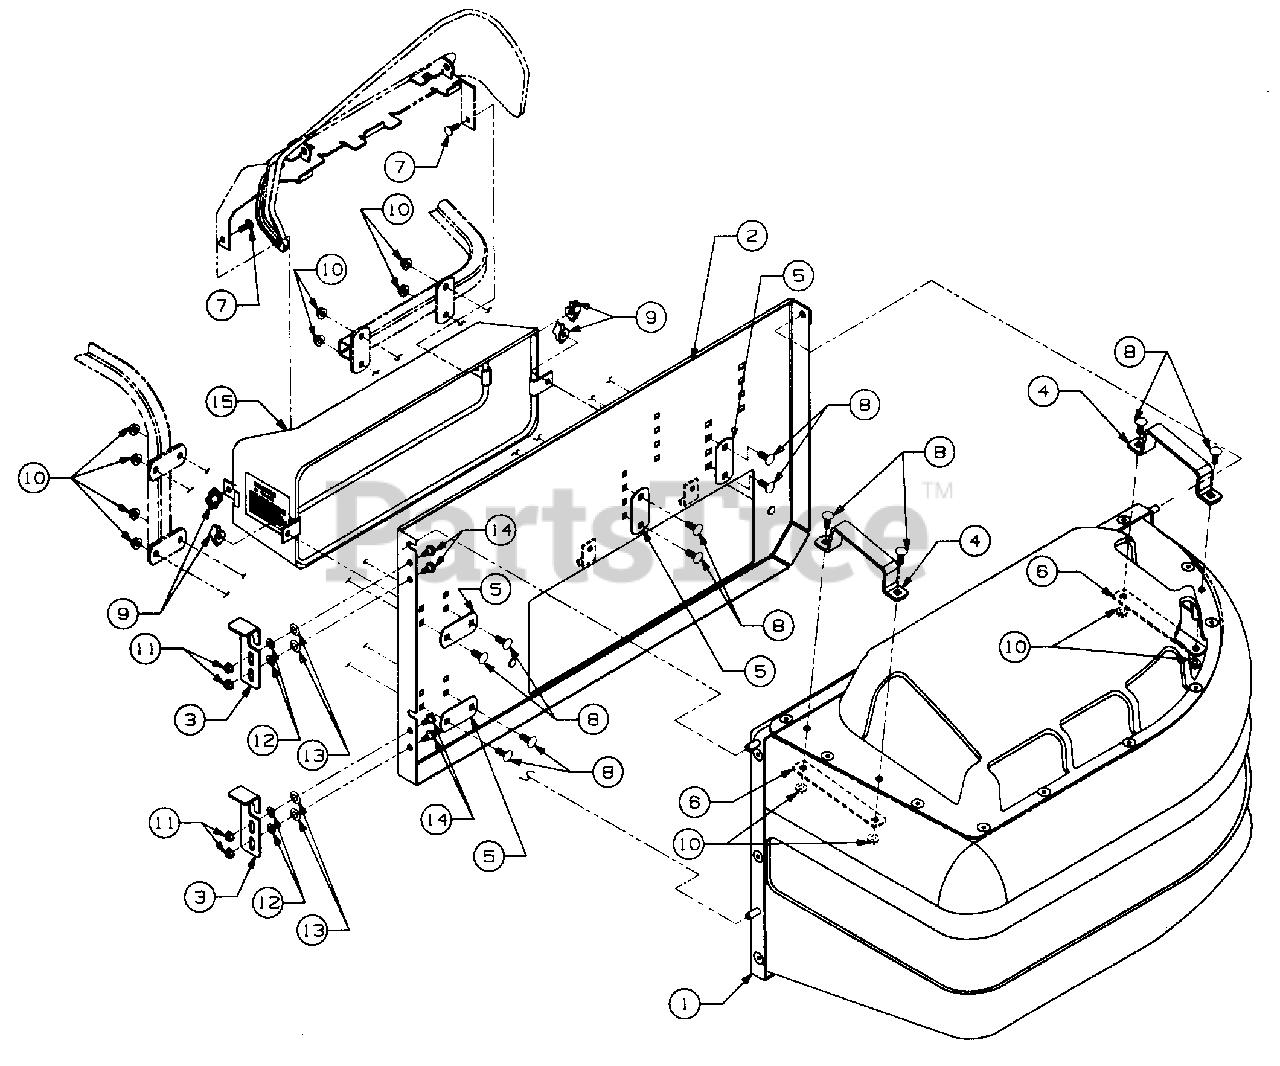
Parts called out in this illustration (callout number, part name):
1	Hopper, Grass
2	Plate, Support
4	Handle, Hopper
5	Plate, Retainer
6	Plate, Handle Reinforcement
7	Bolt, Carriage, 1/4-20 X .62 Lg
8	Bolt, Sht Nk Carriage, 5/16-18 X .75 Lg
9	Nut, Wing, 1/4-20
10	Nut, Hex Flange Top Lock, 5/16-18 GR5
11	Nut, Hex Flange Lock, 1/4-20
12	Washer, Flat, .344 X .62 X .033 Thk
13	Washer, Bowed
14	Bolt, Shoulder, 1/4-20 X 2.65 Lg
15	Boot, Grass Catcher
